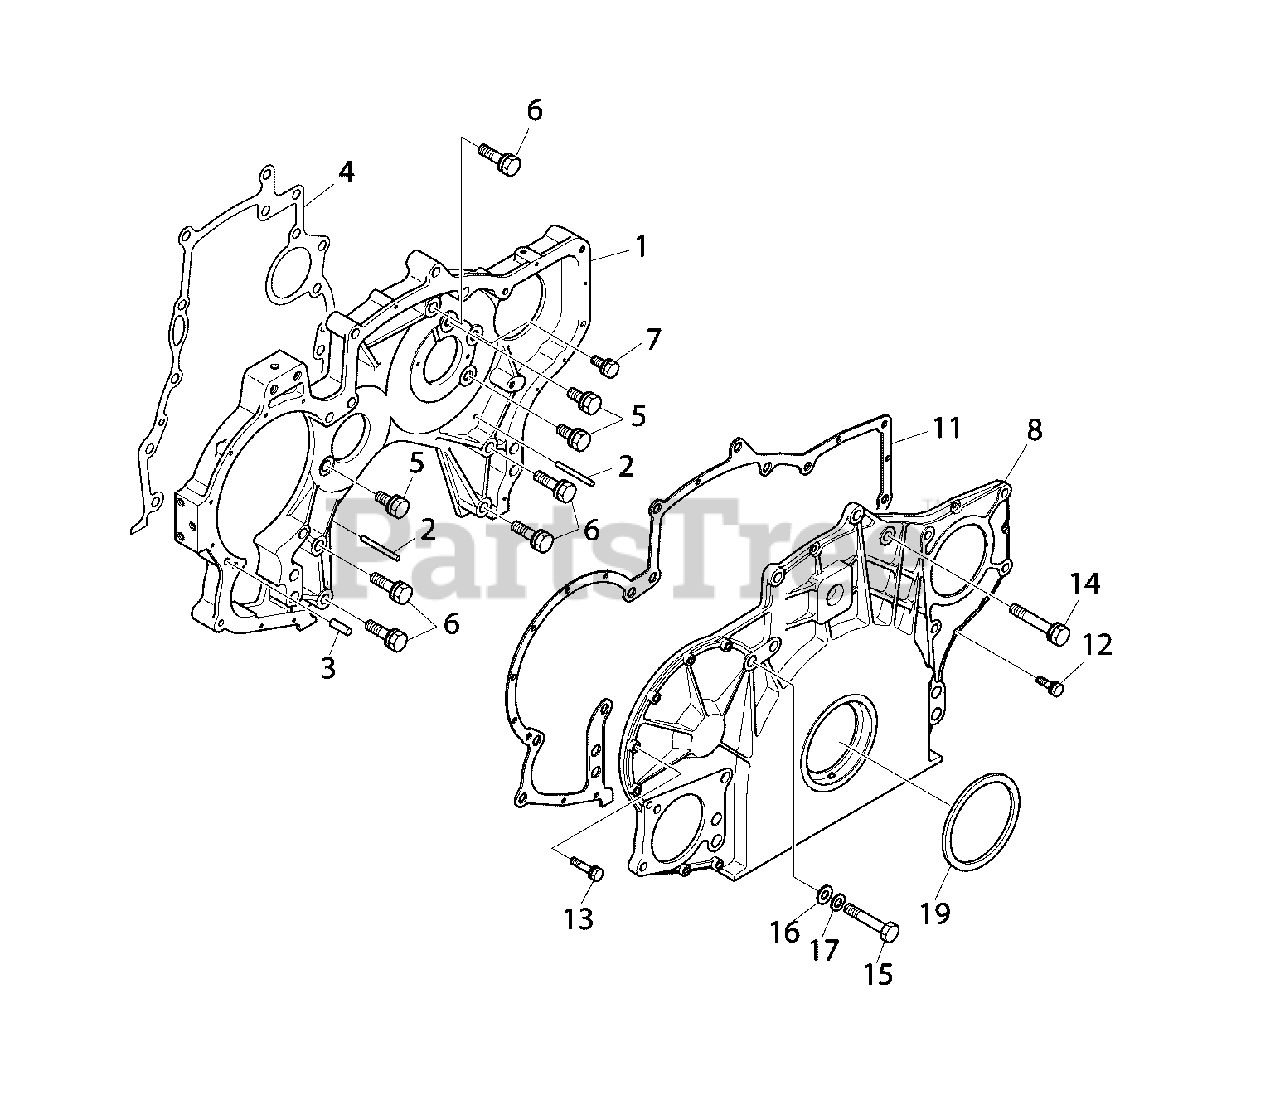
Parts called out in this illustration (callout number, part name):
1	* CASE, T/GEAR
2	* PIN, DOWELL
3	* PIN, DOWELL
4	* GASKET
5	* BOLT
6	* BOLT
7	* BOLT
8	* COVER, T/G CASE
11	* GASKET, T/G CASE
12	* BOLT, HEX
13	* BOLT
14	* BOLT
15	* BOLT, HEX
16	* WASHER, SPRING
17	* WASHER, SPRING
19	SEAL, OIL (FRONT)
